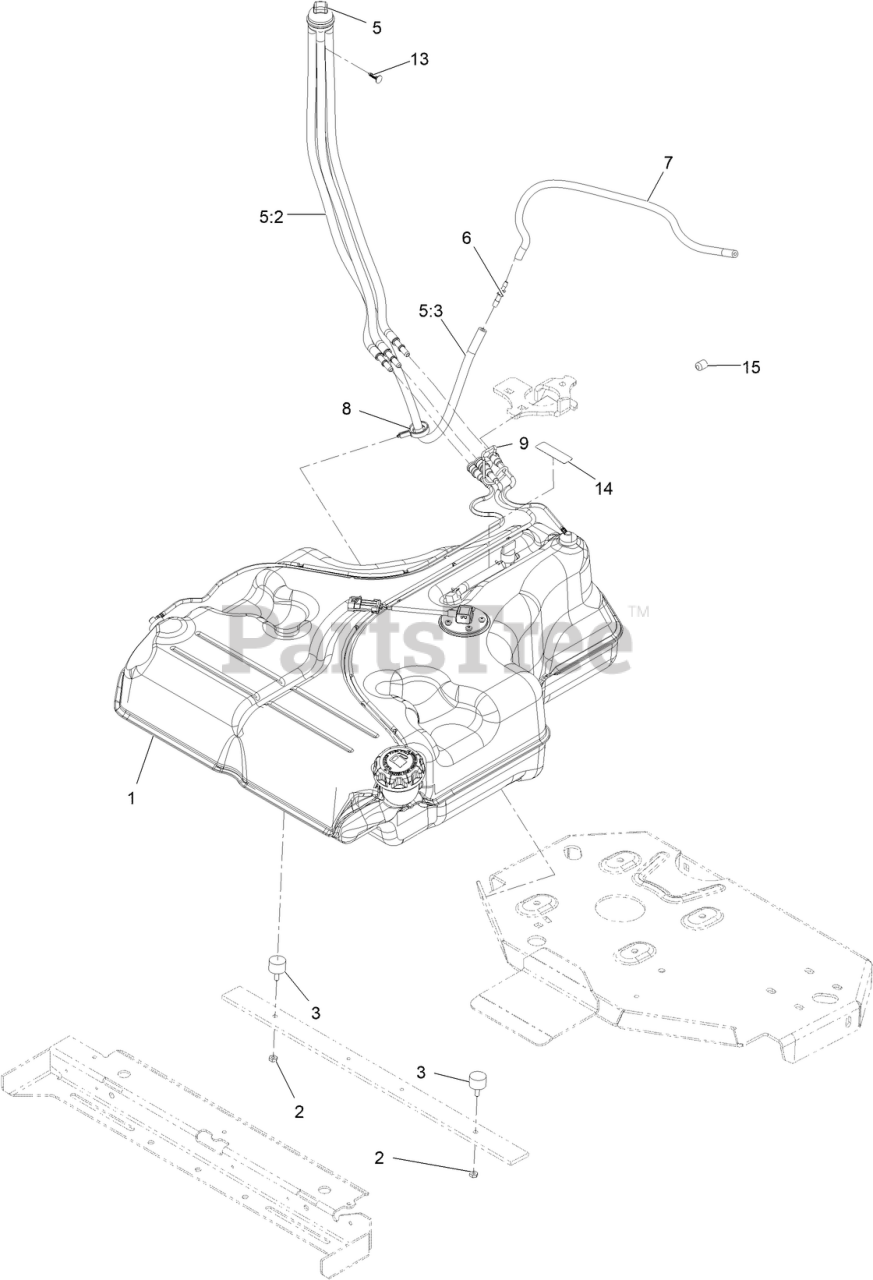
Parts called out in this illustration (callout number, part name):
1	FUEL TANK ASM
2	NUT-JAM
5	FUEL MANIFOLD VENT ASM
5:2	HOSE-FUEL
5:3	HOSE-FUEL
6	BARB-FUEL
7	HOSE-FUEL
8	CLAMP-HOSE
9	RETAINER-LINE, VAPOR
13	PLUG-PLASTIC
14	DECAL-STRIP BLACK
15	PLUG-PORT
